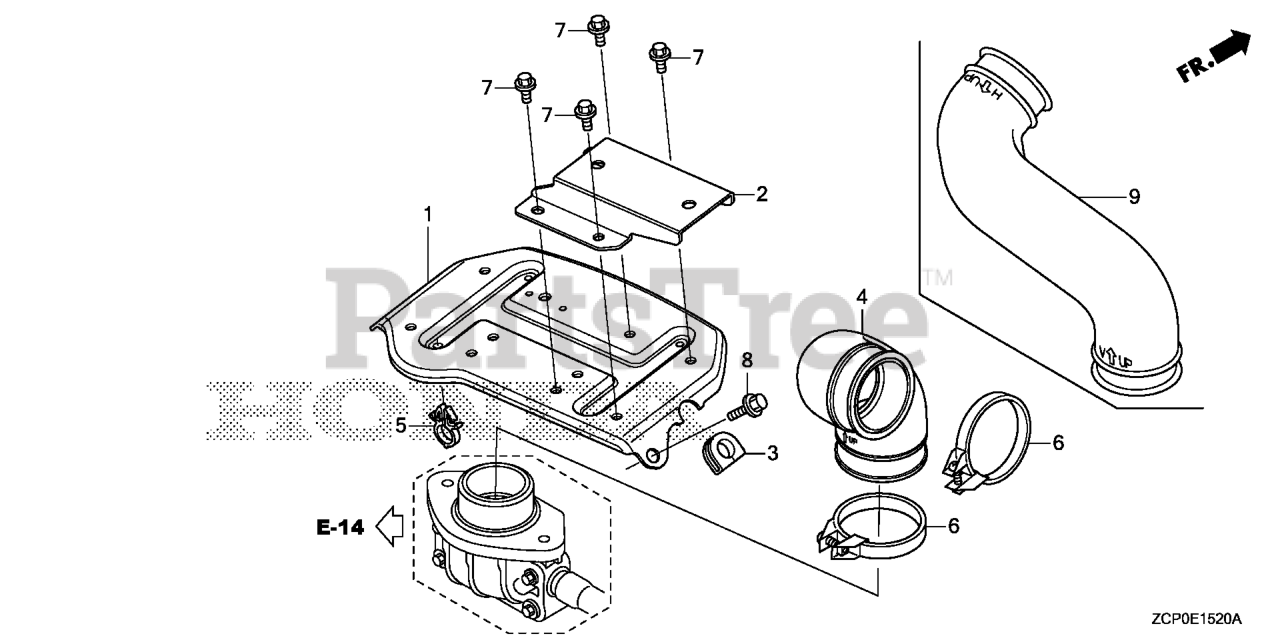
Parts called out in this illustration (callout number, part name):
1	STAY, AIR CLEANER
2	SUB-STAY, AIR CLEANER
3	GROMMET, AIR CLEANER STAY
4	TUBE, AIR CLEANER CONNECTING
5	CLIP, WIRE HARNESS
6	BAND, AIR CLEANER CONNECTING TUBE (58)
7	BOLT, FLANGE (6X12) Use up to Engine SN 1543277.
8	BOLT, FLANGE (8X16) Use from Engine SN 1000016.
